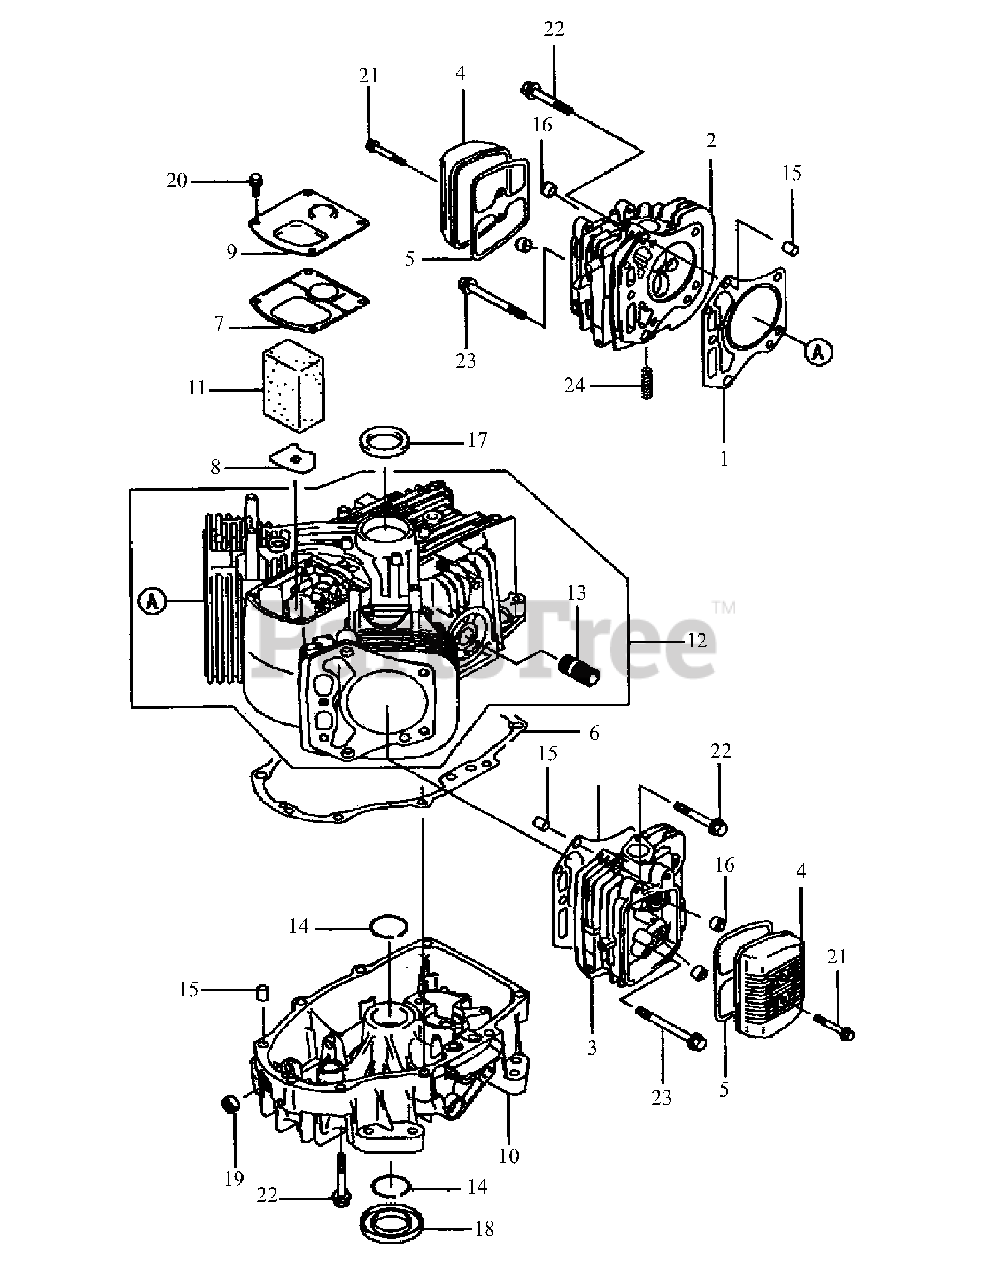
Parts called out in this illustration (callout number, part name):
2	Head, Complete Cylinder #1
3	Head, Complete Cylinder #2
5	Gasket, Rocker Case
6	Gasket, Crankcase Cover
9	Cover
10	Cover, Crankcase
11	Element, Breather
12	Crankcase, Complete
20	Bolt, Flanged
22	Bolt, Flanged
23	Bolt, Flanged
